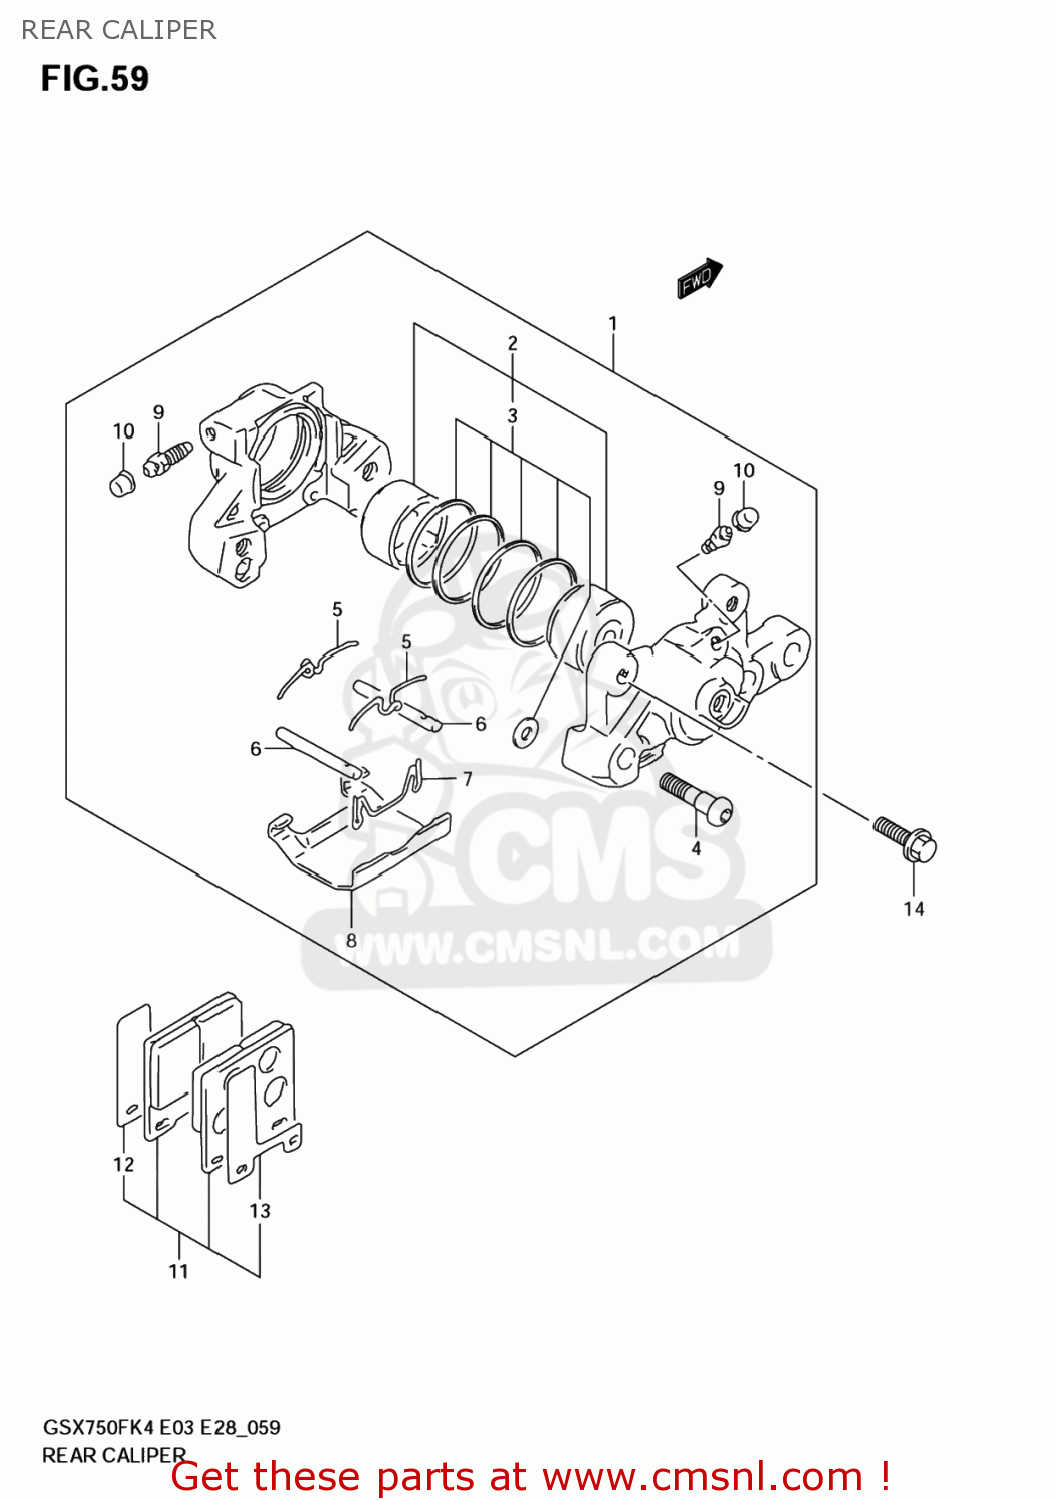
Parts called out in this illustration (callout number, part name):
1	CALIPER ASSY,RR
2	PISTON SET
3	SEAL SET,PISTO
4	BOLT,HOUSING
5	SPRING
6	PIN,PAD
7	CLIP,PAD PIN
8	COVER
9	BLEEDER
10	CAP,BLEEDER PLUG
11	PAD & SHIM SET (NAS)
12	SHIM,INNER
13	SHIM,OUTER
14	BOLT
